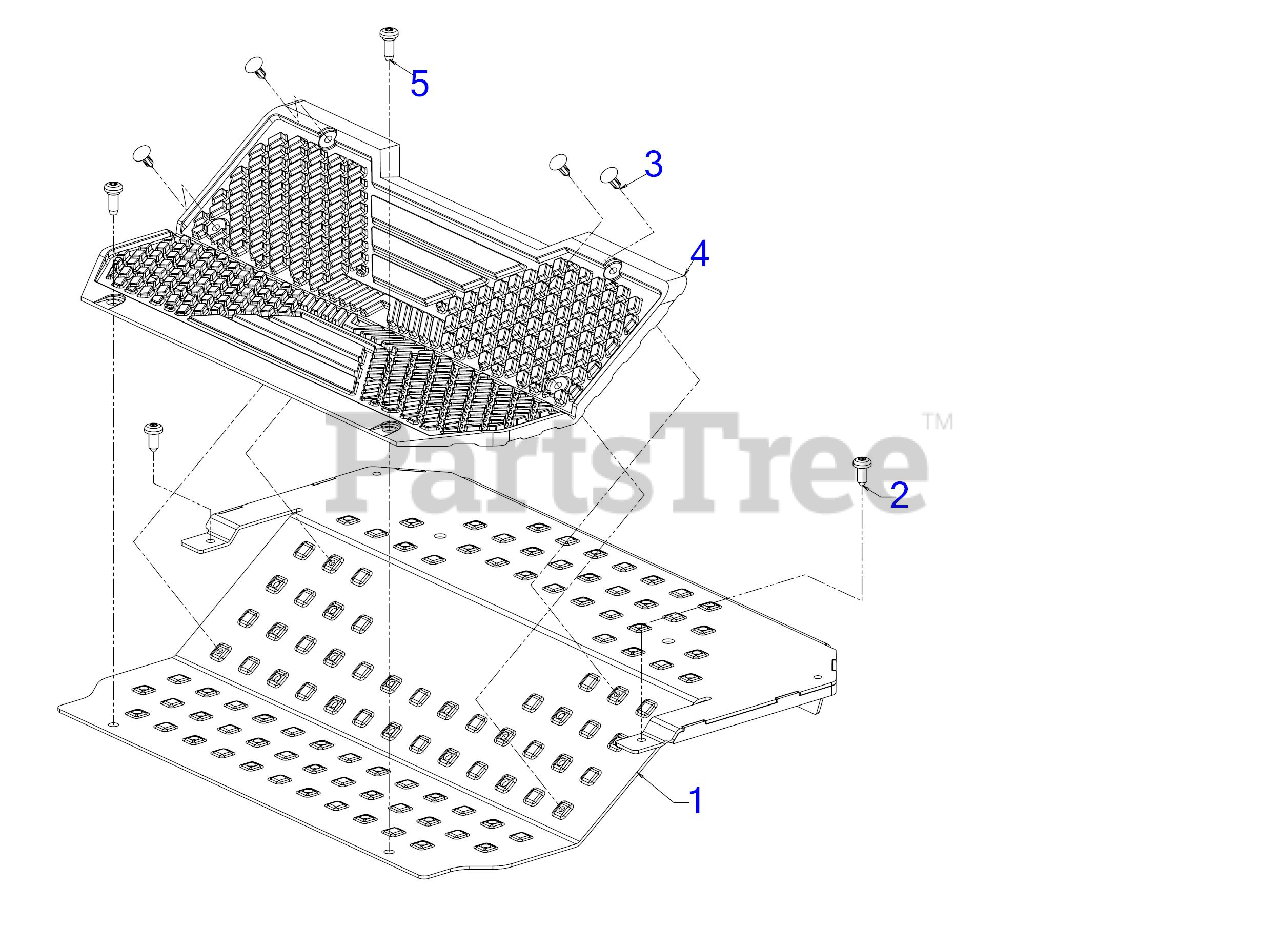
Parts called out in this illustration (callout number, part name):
2	SCREW 5/16-18 x .750
3	RATCHET CLIP .250
4	FLOORBOARD PAD
5	SHOULDER SCREW 5/16-18X.75
